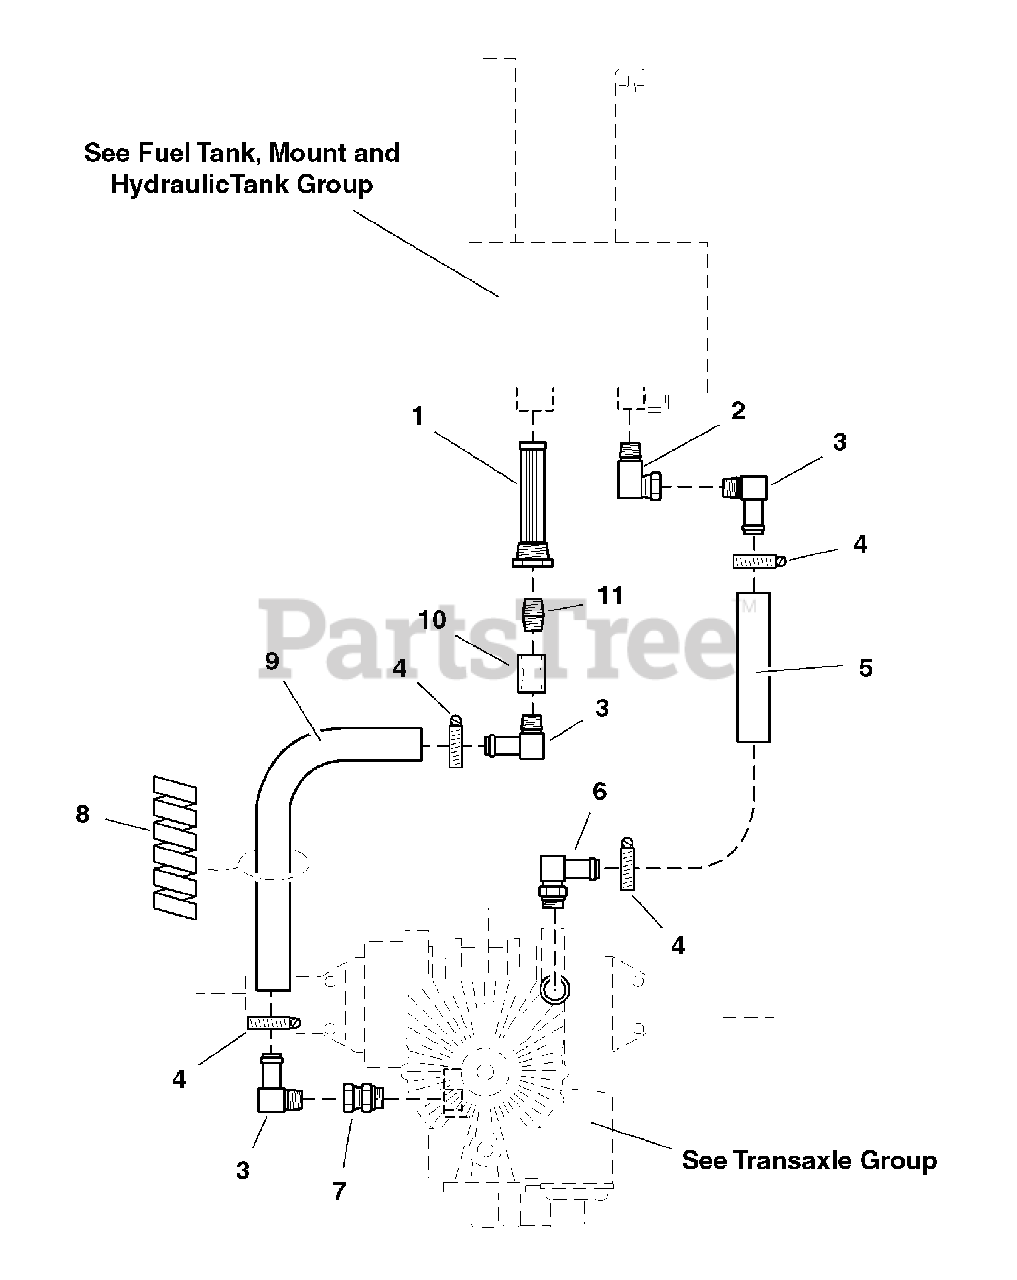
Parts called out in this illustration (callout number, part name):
2	FITTING, 1/2 NPT Swivel, 90 Deg.
3	FITTING, 1/2 NPT - 3/4 Hose, 90 Deg.
4	HOSE CLAMP, #10
6	FITTING, 7/8 O-Ring - 3/4 Hose, 90 Deg.
7	FITTING, 7/8 O-Ring - 1/2 NPT, Swivel
8	PROTECTIVE COIL, 12"
10	COUPLER, 1/2 NPT
11	CLOSE NIPPLE, 1/2 NPT
